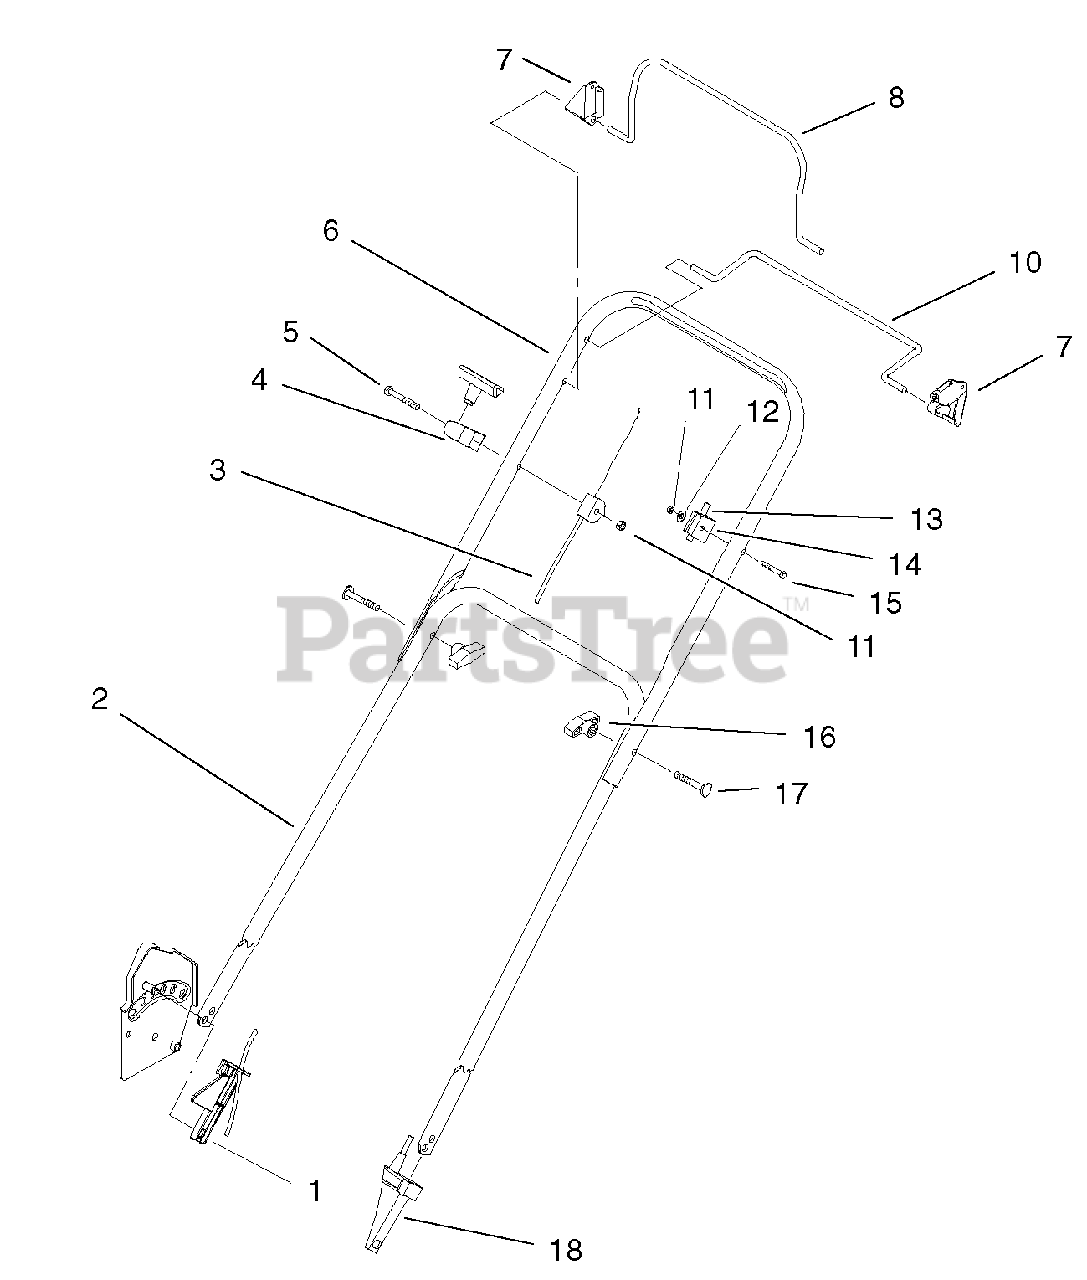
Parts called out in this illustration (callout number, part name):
1	Guard-Cable
2	Handle-Lower
3	Brake Cable ASM
4	Guide-Rope
5	Screw-HH
6	Handle-Upper
7	Stop-Pivot
8	Bail-Brake
10	Bail-Control
11	Nut-Lock, NI
12	Washer-Flat
13	Cable-Ground Speed
14	Anchor-Upper, Cable
15	Screw-Handle
16	Knob-Handle
18	Anchor-Cable
